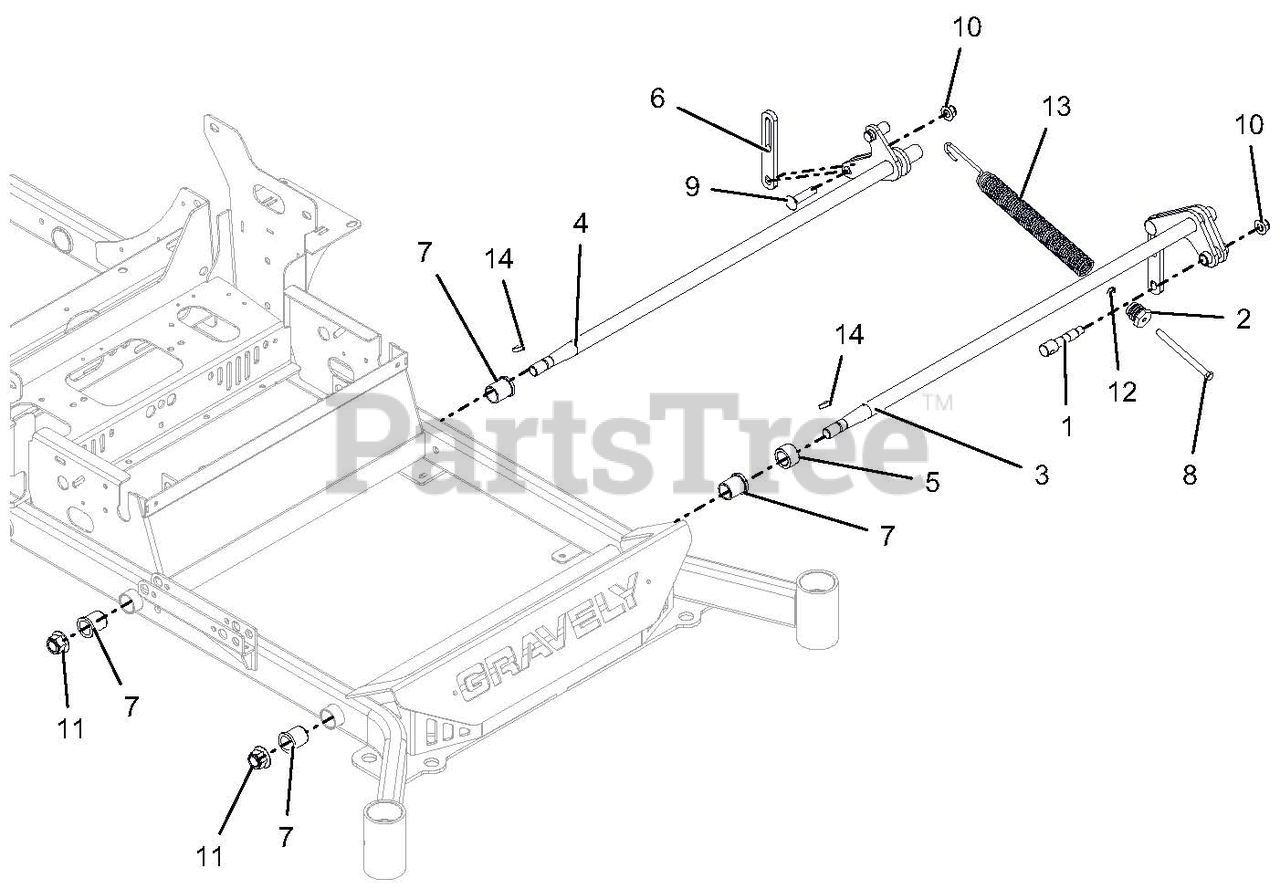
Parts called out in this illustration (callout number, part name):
1	TRUNION, DECK LIFT SPRING
2	PLUG, SPRING
3	FRONT LH DECK LIFT ARM WMT -LF
4	REAR LH DECK LIFT ARM WMT -LF
5	SPACER, 1.500 X 1.000 X .880
6	LINK-DECK LIFT - LONG
7	BSHG-FLG 1.00X1.25X1.50X1.50
8	BLT-HEX .38-16X5.00 GR5 FTH YZ
9	BLT-RDHDSQNK .50-13X2.25 G5YZ
10	@NUT-LK-NYL-FLG .50-13 YWZC
11	@NUT-LK-NYL-FLG .75-10 YWZC
12	NUT-HEX-JAM .375-16 YWZC
13	SPRING, DECK LIFT
14	KEY-WDRF .25X1.00 HRD #15
